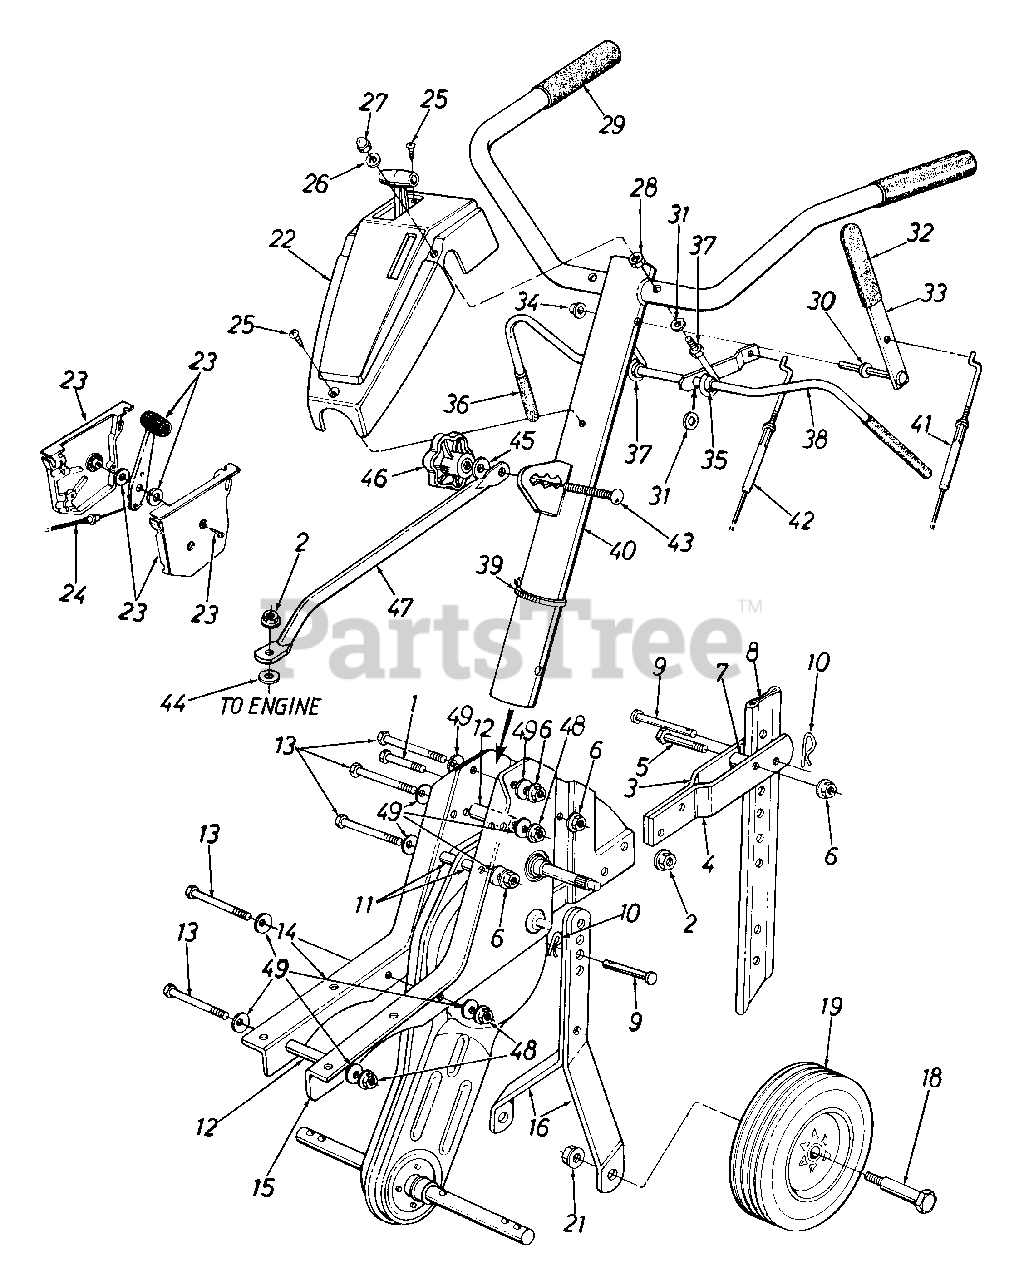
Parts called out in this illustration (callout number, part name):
1	Hex Bolt 5/16-18 x 1.25" Lg.
2	Hex Flange L-Nut 5/16-18 Thd. (Gr. 5)
5	Hex Bolt 5/16-18 x 1.5" Lg.
6	Hex Flange L-Nut 5/16-18 Thd. (Gr. 5)
7	Spacer .32" I.D. x .75" O.D.
9	Clevis Pin .375" I.D. x 1.75" Lg.
10	Internal Cotter Pin
11	Spacer .326" I.D. x .47" O.D.
12	Spacer .322" I.D. x .44" I.D.
13	Hex Bolt 5/16-18 x 2.75" Lg.
19	Wheel Ass'y. 8" x 1.75"
21	Hex Flange L-Nut 3/8-16 Thd. (Gr. 5)
22	Handle Cover w/Reverse
23	Throttle Control Box Ass'y.
24	Throttle Control Wire 35" Lg.
25	Truss Mach. AB-Tap Scr. #10 x .5" Lg.
26	Fl-Wash. .266" I.D. x .625" O.D.
27	Hex L-Stop Nut 1/4-28 Thd.
28	Hex Nut 1/4-28 Thd.
29	Grip - Handle
30	Fl-Wash. .344" I.D. x .62" O.D.
31	Fl-Wash. .385" I.D. x .62" O.D.
32	Grip - Reverse Lever
33	Reverse Handle Ass'y.
34	Cap Speed Nut
35	Plastic Bushing .38" I.D.
36	Grip - Clutch
37	Clutch Handle Eye Bolt
42	Clutch Control Cable - Forward
43	Carr. Bolt 5/16-18 x 1" Lg. (Special)
44	Fl-Wash. .344" I.D. x 1.12" O.D.
45	Bell-Wash. .345" I.D. x .88" O.D.
46	Hand Knob
49	Bell-Wash. .345" I.D. x .88" O.D.
